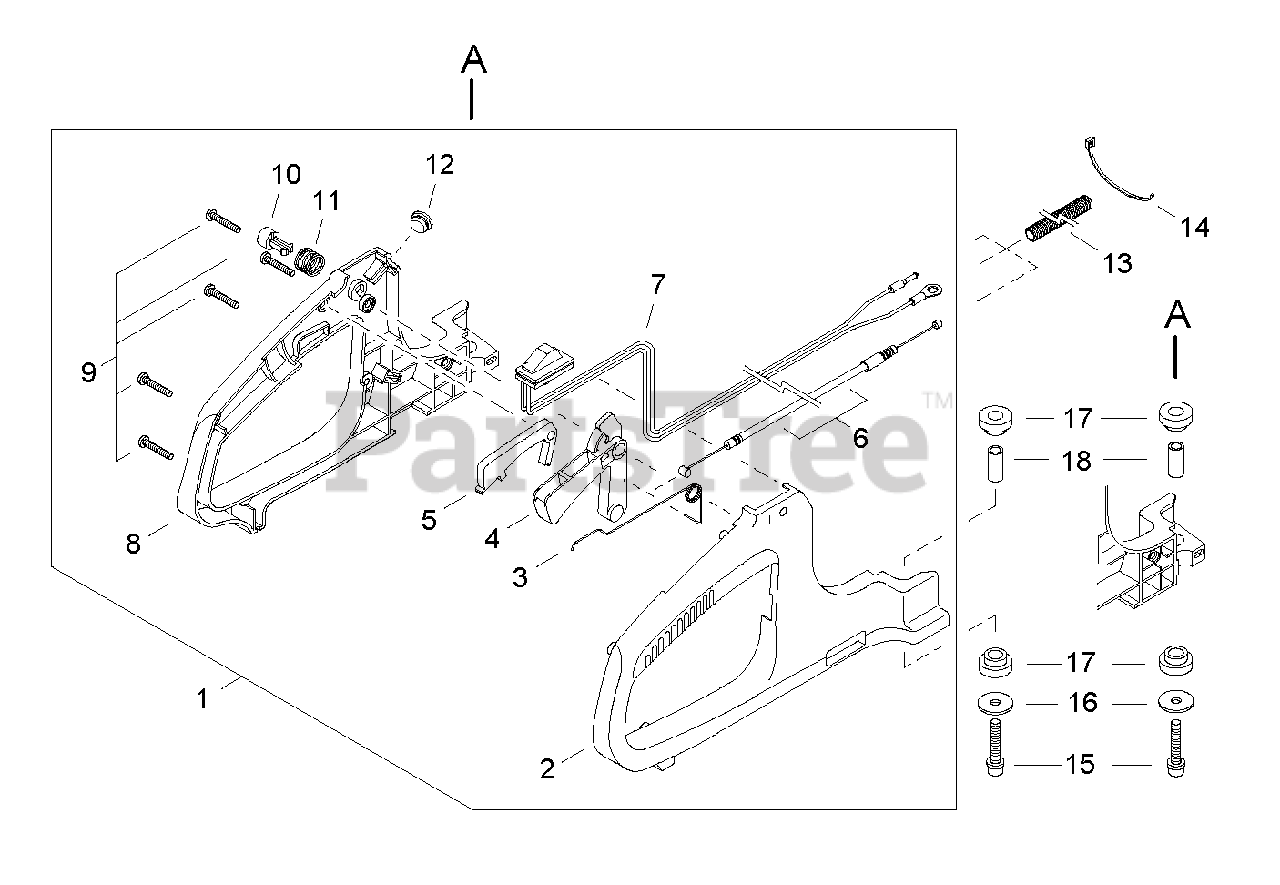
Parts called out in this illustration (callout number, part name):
1	HANDLE ASSY - REAR
2	HANDLE - RIGHT
3	SPRING, TRIGGER
4	TRIGGER, THROTTLE
5	LEVER, TRIGGER LOCKOUT
6	CABLE, THROTTLE
7	SWITCH, IGNITION
8	HANDLE - LEFT
9	SCREW - 4X18 -- TAPPING
10	BUTTON, THROTTLE LOCK
11	SPRING
12	PLUG
13	TUBE, FLEXIBLE
14	TIE, CABLE
15	SCREW - 6X35
16	WASHER
17	CUSHION
18	COLLAR - 6
